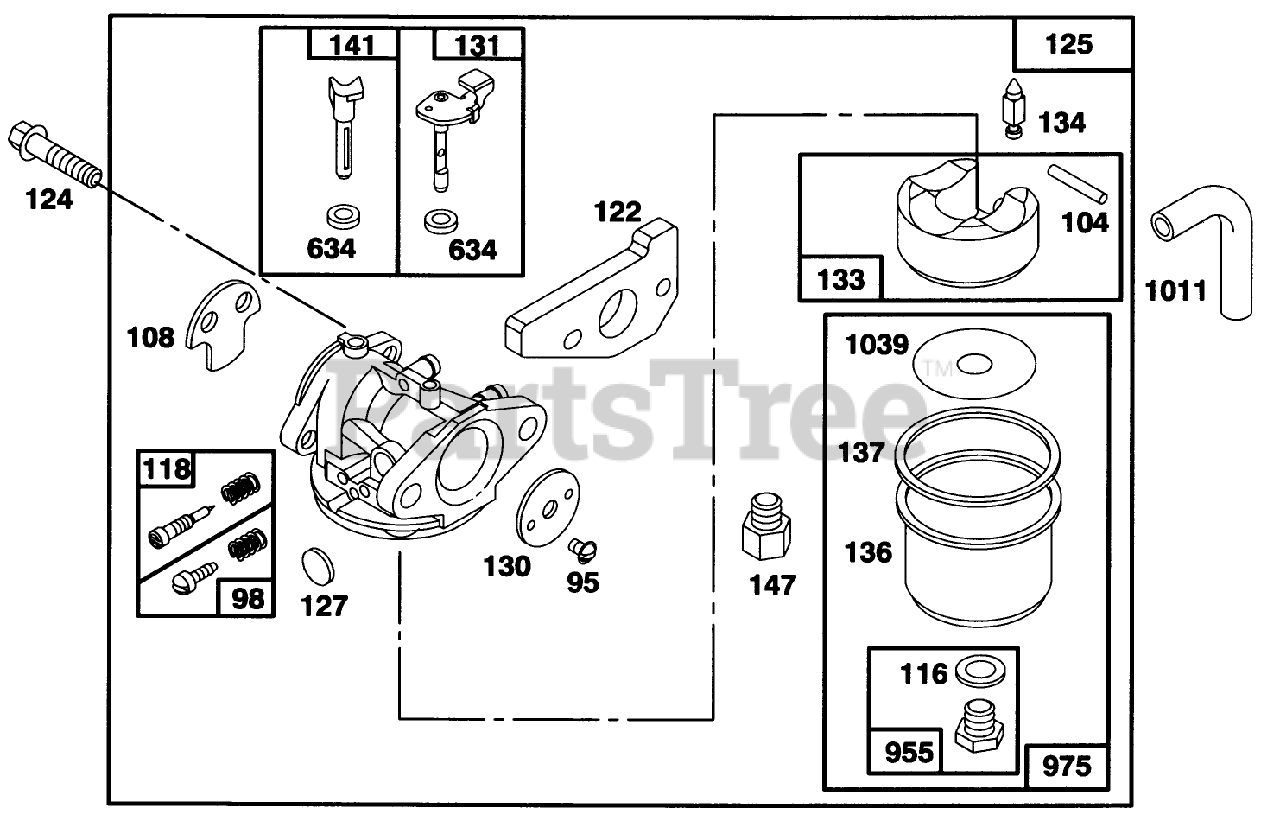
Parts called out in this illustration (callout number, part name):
98	IDLE ADJUSTING SCREW
116	SEALING GASKET
118	VALVE KIT - NEEDLE
122	ADAPTER ASSEMBLY
124	HEX HEAD SCREW
130	THROTTLE VALVE
133	FLOAT-CARBURETOR
134	VALVE-FLOAT
136	Bowl-Fuel
137	FLOAT BOWL GASKET
147	JET ADAPTER
634	Washer-Seal
955	Screw-Hex Head
1011	VENT TUBE
1039	FLOAT LIMITER
